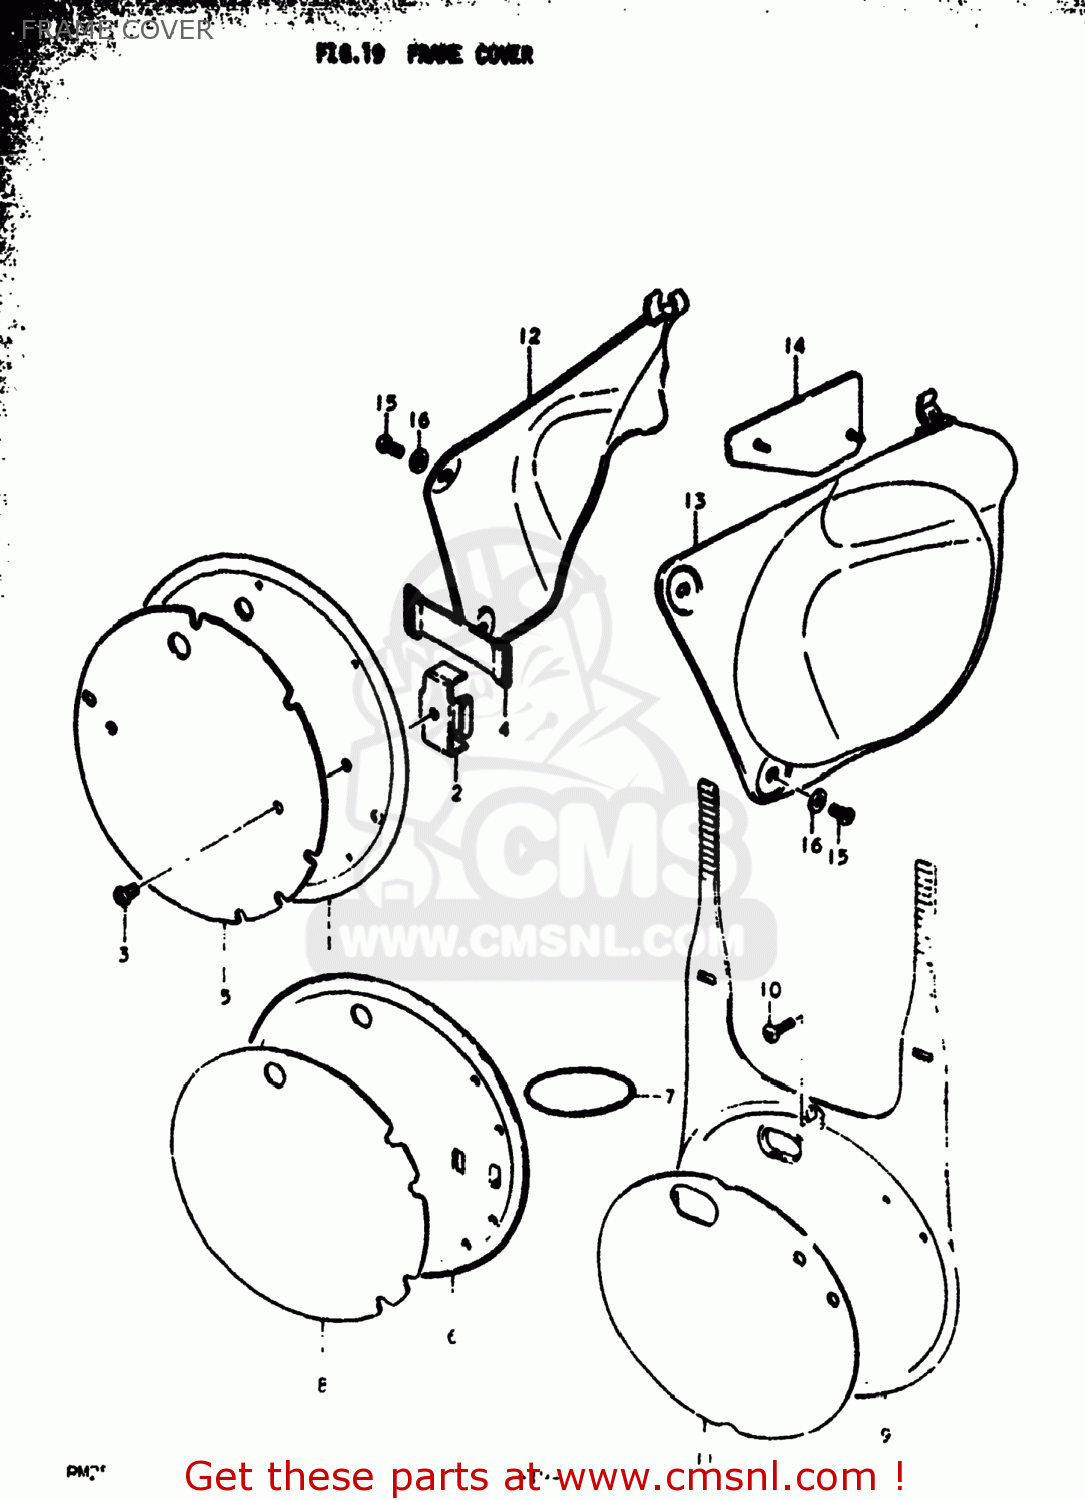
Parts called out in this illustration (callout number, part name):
1	PLATE SET,FRONT
3	SCREW 6X12
4	BAND
5	EMBLEM,FRONT NUMBER PLATE
6	PLATE,NUMBER,FRONT
7	O RING(D:3.53,ID:69.44)
8	EMBLEM,FRONT NUMBER PLATE
9	PLATE,FR NUMBER
10	(5X20) CROSS SCREW
11	EMBLEM,FRONT NUMBER PLATE
12	COVER,FRAME,RIGHT
13	COVER,FRAME,LEFT
15	SCREW 6X12
16	WASHER
